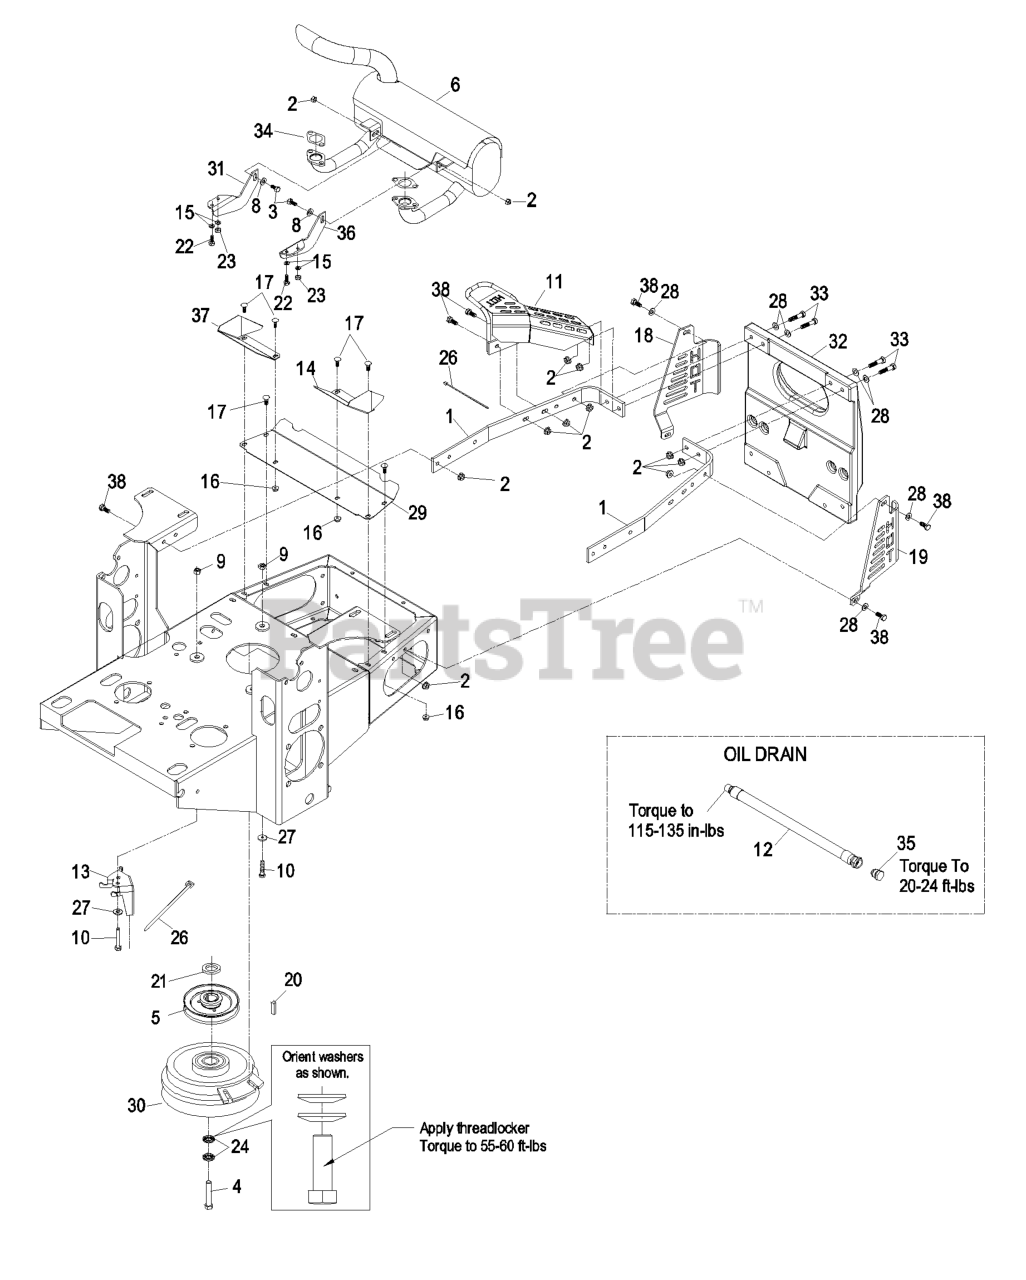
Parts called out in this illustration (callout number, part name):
1	STRAP-GUARD, RH
3	SCREW-HH
4	SCREW-HH
5	PULLEY
6	KIT,MUFFLER (18-23 KOH)
7	WASHER-LOCK
8	WASHER-FLAT
10	SCREW-HH
11	GUARD-TAILPIPE
13	ANCHOR,CLUTCH HD
14	DEFLECTOR-AIR, LH,KC
15	WASHER-LOCK
17	SCREW-CARR
18	GUARD-MUFFLER, RH
19	GUARD-MUFFLER, LH
21	SPACER-CRANKSHAFT
22	SCREW-HH
23	NUT-HEX
24	WASHER-SPRING
25	SCREW-HH
26	TIE-PLASTIC
27	WASHER-SPRING
28	WASHER-PLAIN
29	DEFLECTOR-SHORT
30	CLUTCH KIT
31	BRACKET-MUFFLER, RH
32	WEIGHT-NOTCHED, 60 LB
33	SCREW-HH
36	BRACKET-MUFFLER, LH
37	DEFLECTOR-AIR, RH,KC
38	SCREW-HH
